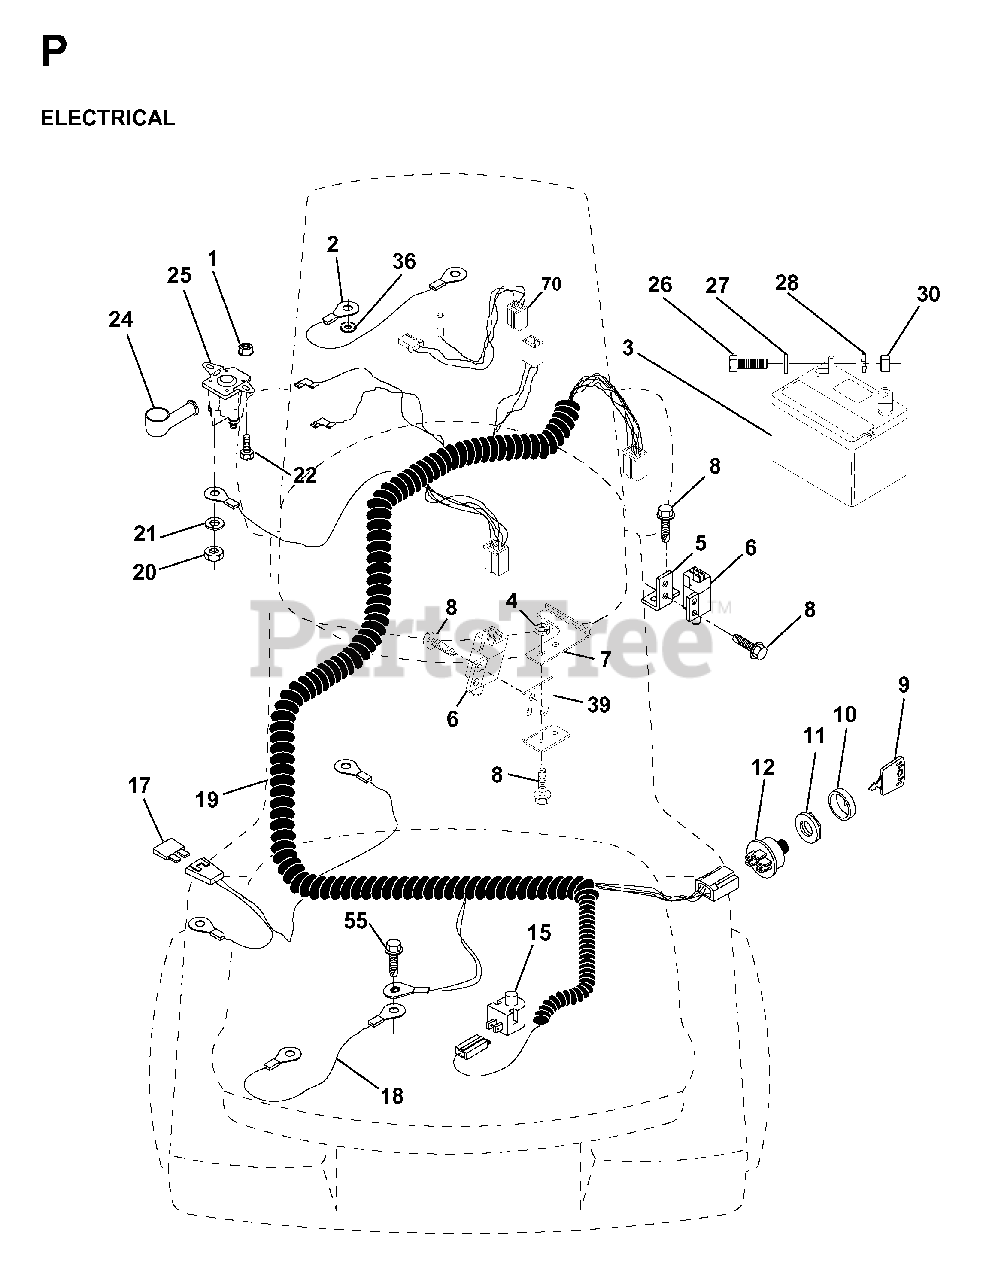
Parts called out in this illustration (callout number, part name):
2	CABLE ASM
5	BRACKET LT
6	SWITCH INTERLOCKT
7	KEEPER, ACTUAT. L.R.
9	KEY-STEEL DELTA
10	COVER SWITCH KEY
11	NUT, IGNITION
12	IGNITION SWITCH
15	SWITCH SEAT
19	HARNESS, IGN FEND
20	NUT
21	LOCKWASHER
24	TERMINAL COVER
25	SOLINOID
27	WASHER
28	LOCKWASHER
30	NUT
36	LOCKWASHER
70	HARNESS, ENGINE
